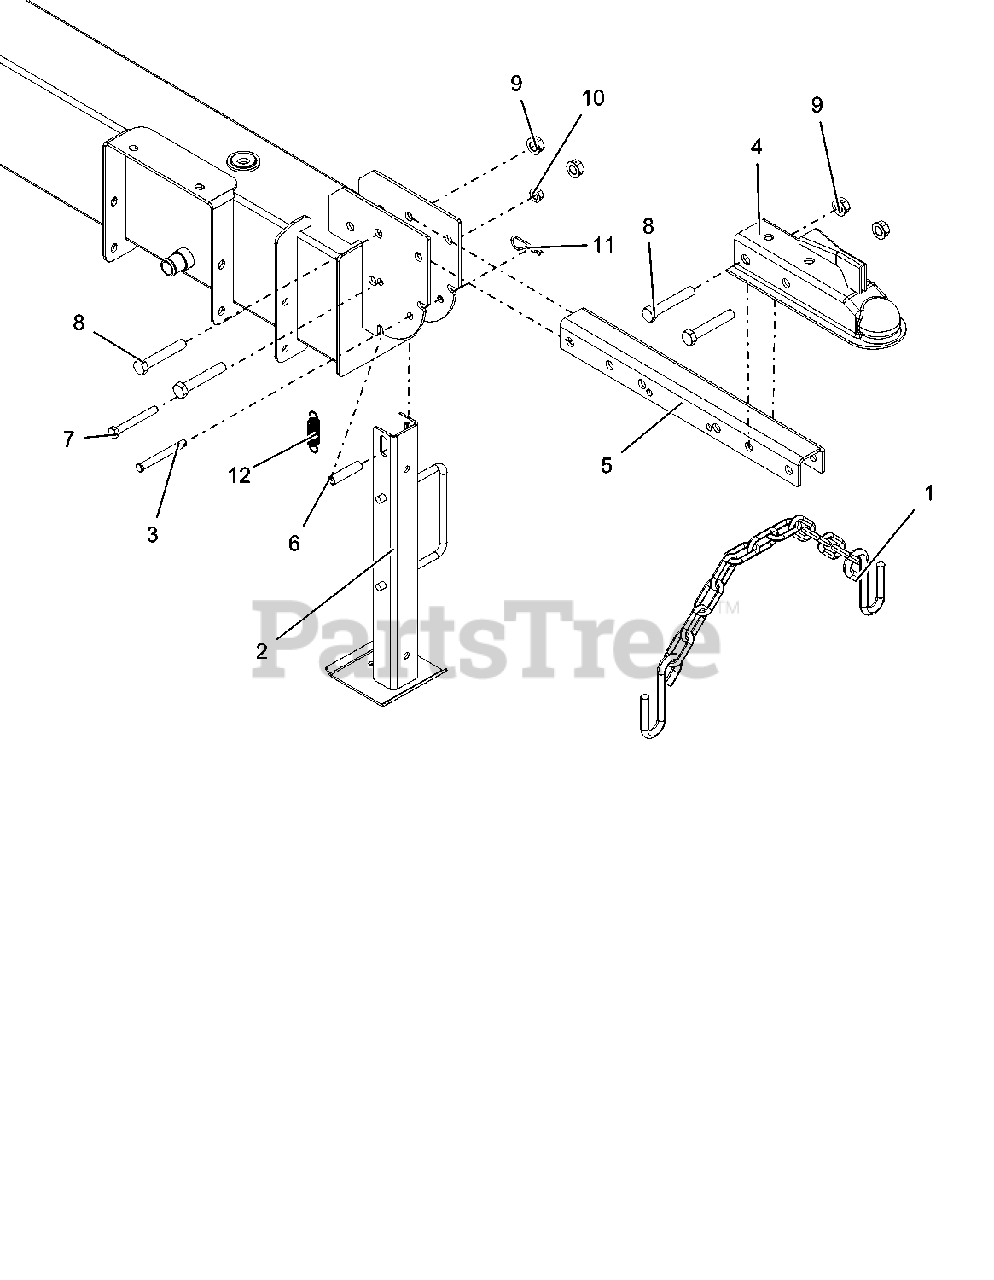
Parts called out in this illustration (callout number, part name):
1	CHAIN, SAFETY
2	WLDMT, JACK STAND
3	PIN, CLEV .375X3.25 YWZC
4	HITCH, BALL - 2"
5	BAR, HITCH
6	SPCR, WHEEL .385X.500X2.00
7	BLT-HEX .38-16X3.00 GR5 YWZC
8	BLT-HEX .50-13X3.00 GR5 YWZC
9	NUT-LK-CTR-FLG .50-13 YWZC
10	NUT, LK-TOP-FLG .38-16 YWZC
11	HAIR, PIN #7 CLIP .094 X 2.31 YWZ
12	SPRG, EXTENSION
